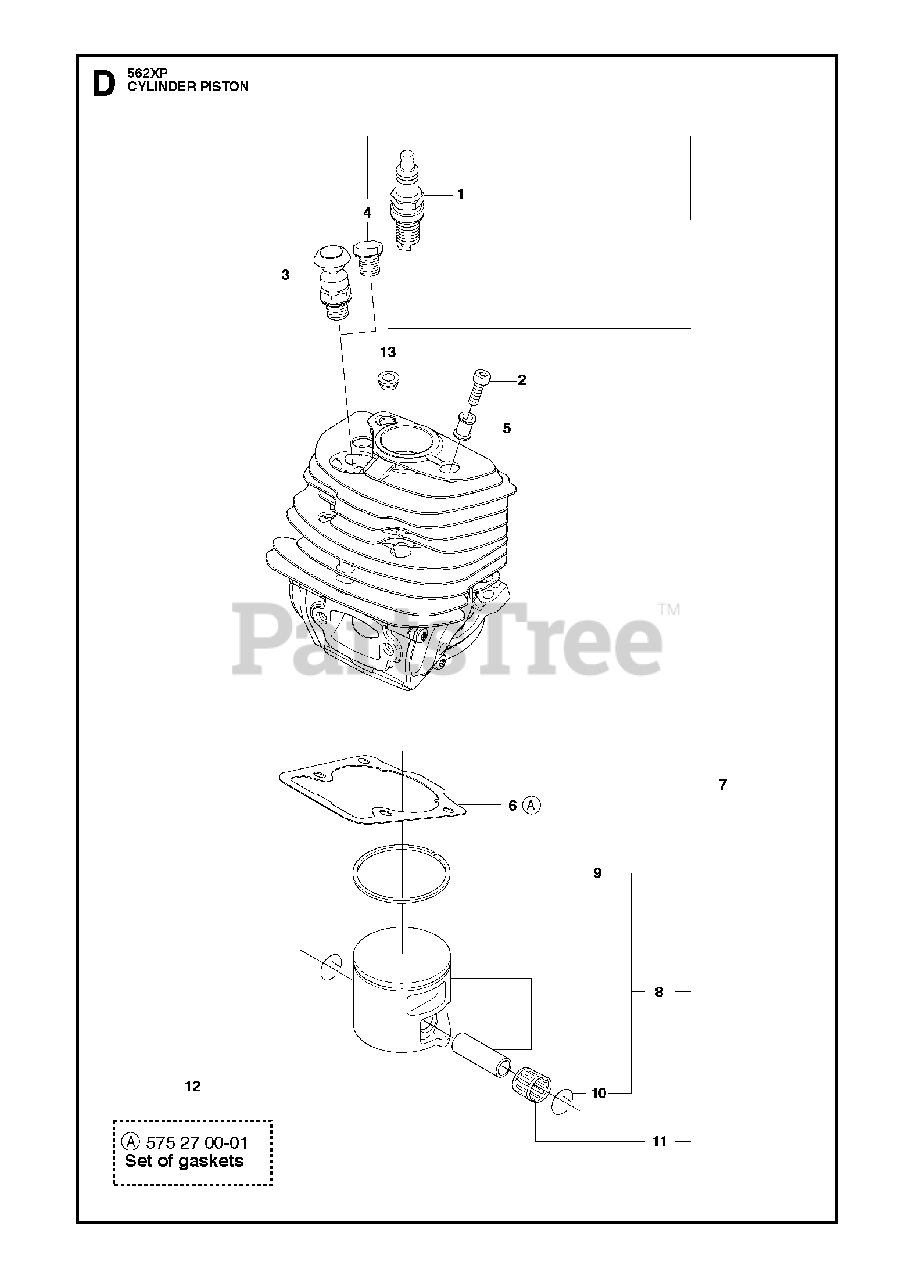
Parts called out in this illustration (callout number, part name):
1	CMR6H SPARK PLUG NGK
2	SCREW MC6S 5X35
3	DECOMPRESSION VALVE
4	CYLINDER PLUG
6	GASKET
7	CYLINDER ASSY
8	PISTON ASSY
9	PISTON RING
10	LOCKING RING
11	NEEDLE BEARING
12	RP GASKET KIT
13	BUSHING
